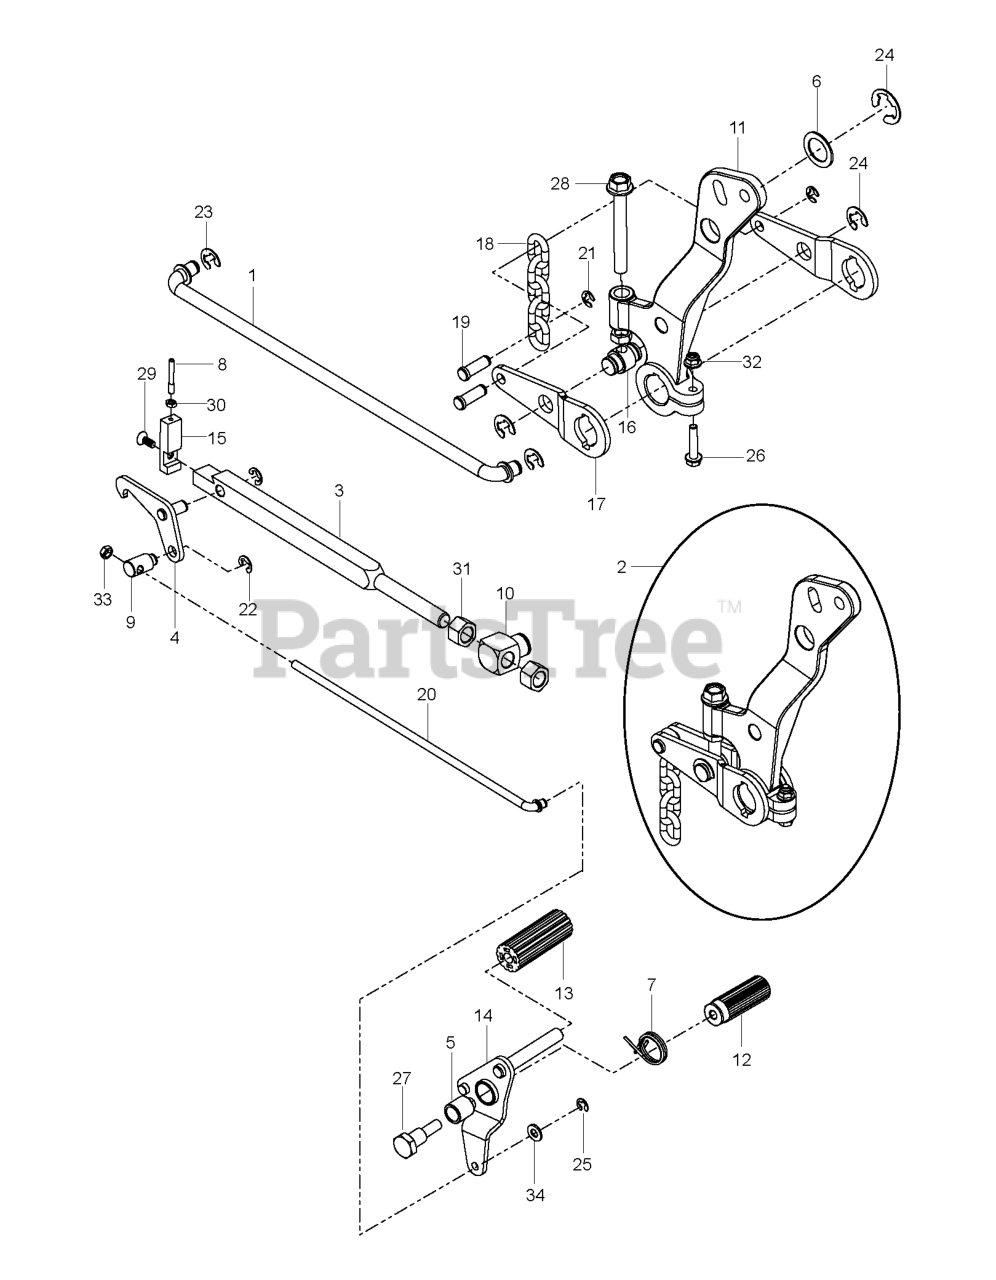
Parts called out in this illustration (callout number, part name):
1	ROD, LIFT
2	ASSEMBLY, DECK LIFT LEVER
3	BAR, HEIGHT
4	LATCH, HEIGHT WLDMT
5	BUSHING, SLEEVE 3/4 X 1.0
6	MACHINE BUSHING
7	SPRING, TORSION
8	LINK, INDICATOR
9	SWIVEL, HEIGHT LATCH
10	SWIVEL, HEIGHT BAR
11	ARM, LIFT LEVER
12	PAD, FOOT PEDAL
13	PEDAL, DECK HEIGHT
14	PEDAL, RELEASE WLDMT
15	CAP, HEIGHT BAR
16	SHAFT, LIFT TRUNION WSL
18	LIFT CHAIN
19	PIN, 7/16 CLEVIS
20	ROD, HEIGHT LATCH
21	RING, E, 7/16
22	E-RING 1/2 (2 2)
23	E-RING 5/8
24	E RING 3/4
25	E RING 3/8"
26	HHFS 5/16-18 X 1.5 GD 5
27	BOLT, SHOULDER
28	HHFS 1/2-13 X 4 GR 5
29	SCREW, 5/16-18 X 3/4 FLAT HEX
30	NUT 1/4-20 JAM
31	NUT 3/4-10 HEX ZD
32	5/16-18 NYLOC FLANGE NUT
33	NUT 3/8-24 JAM
